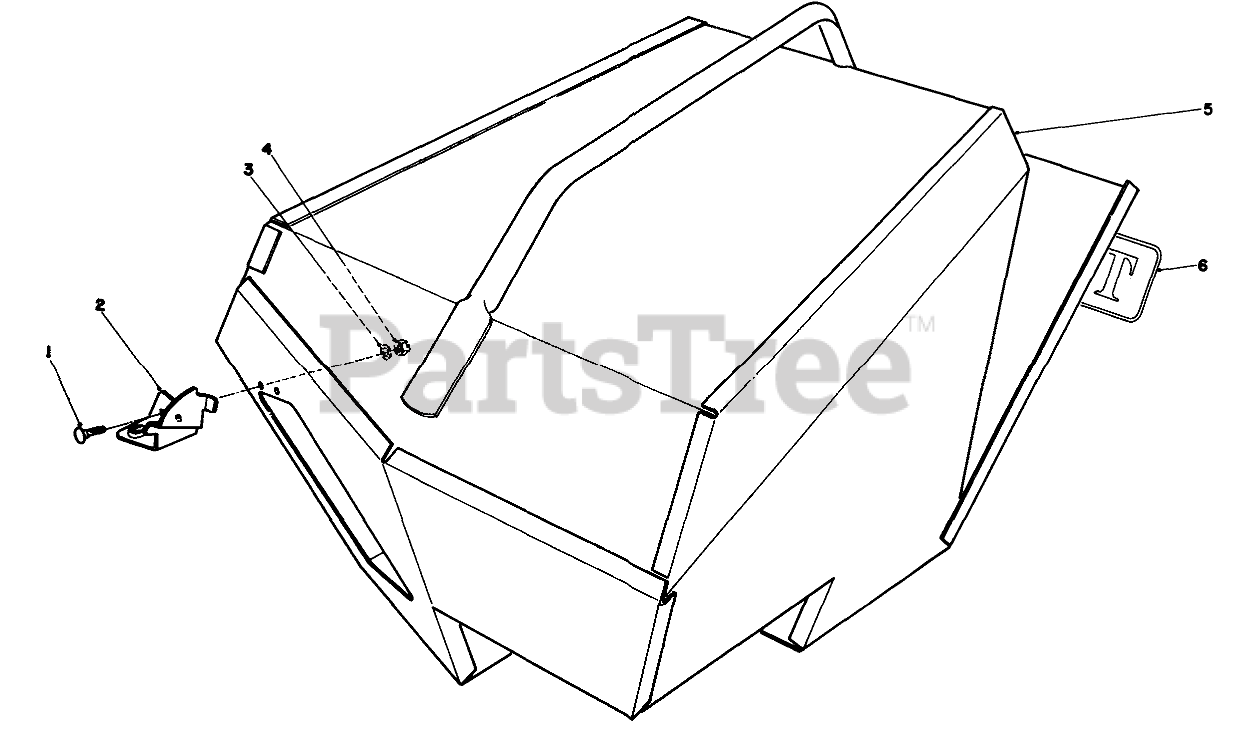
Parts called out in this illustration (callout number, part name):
1	SCREW-CARR
2	Bracket-Latch
3	WASHER-FLAT
4	NUT-LOCK, NI
5	Bag-Steel
6	Decal
